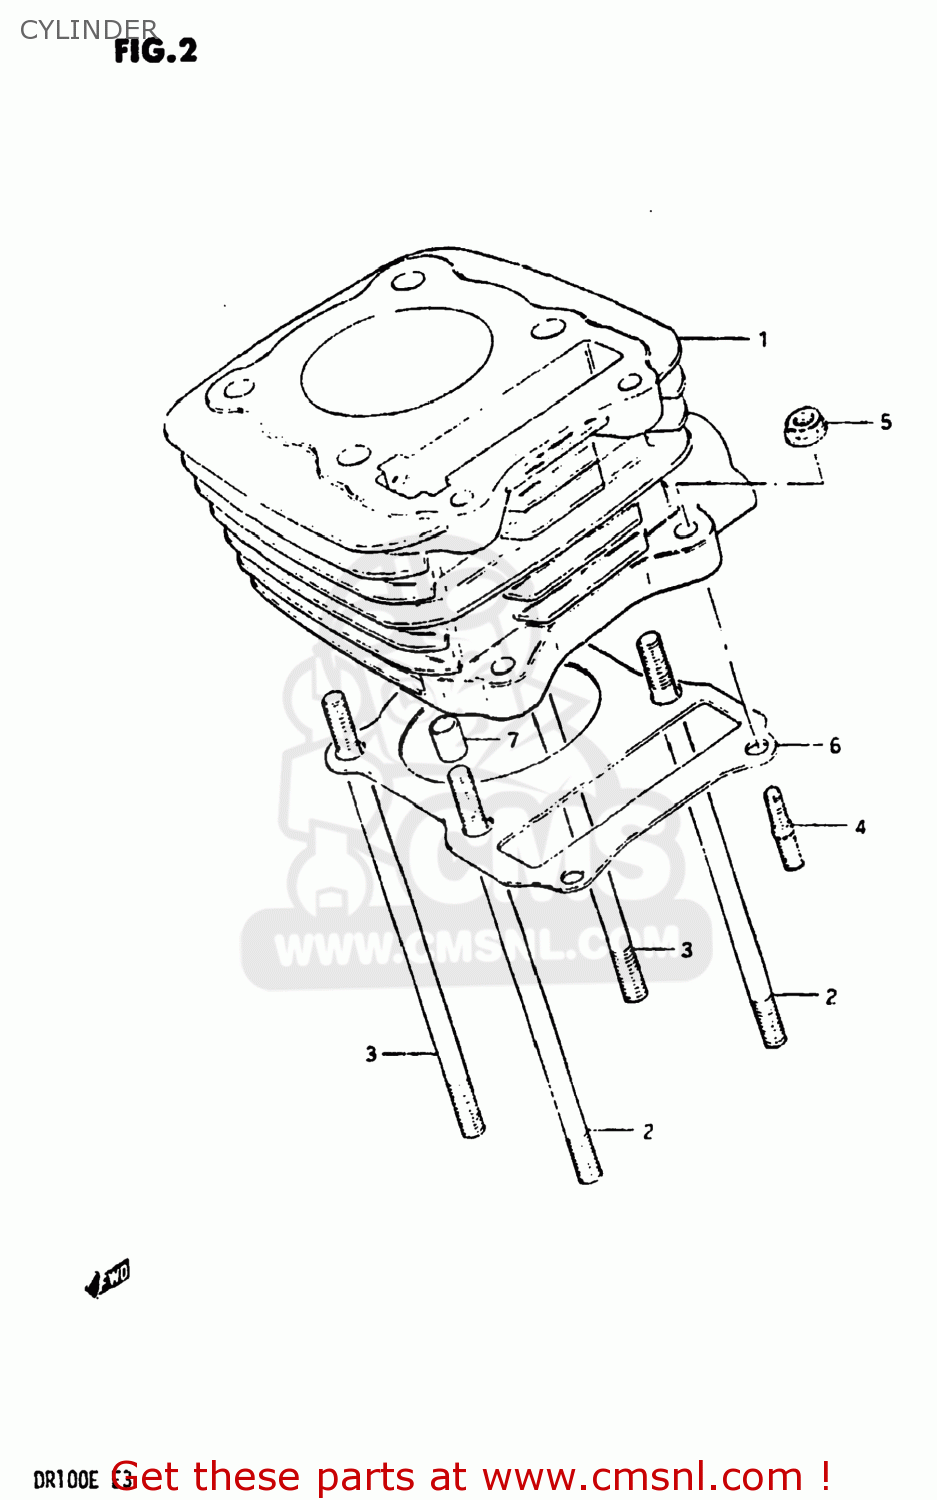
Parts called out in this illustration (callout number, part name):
1	CYLINDER
2	BOLT,STUD
3	BOLT,STUD
4	STUD 6X25
5	NUT
6	GASKET,CYLINDER (MCA)
7	PIN
